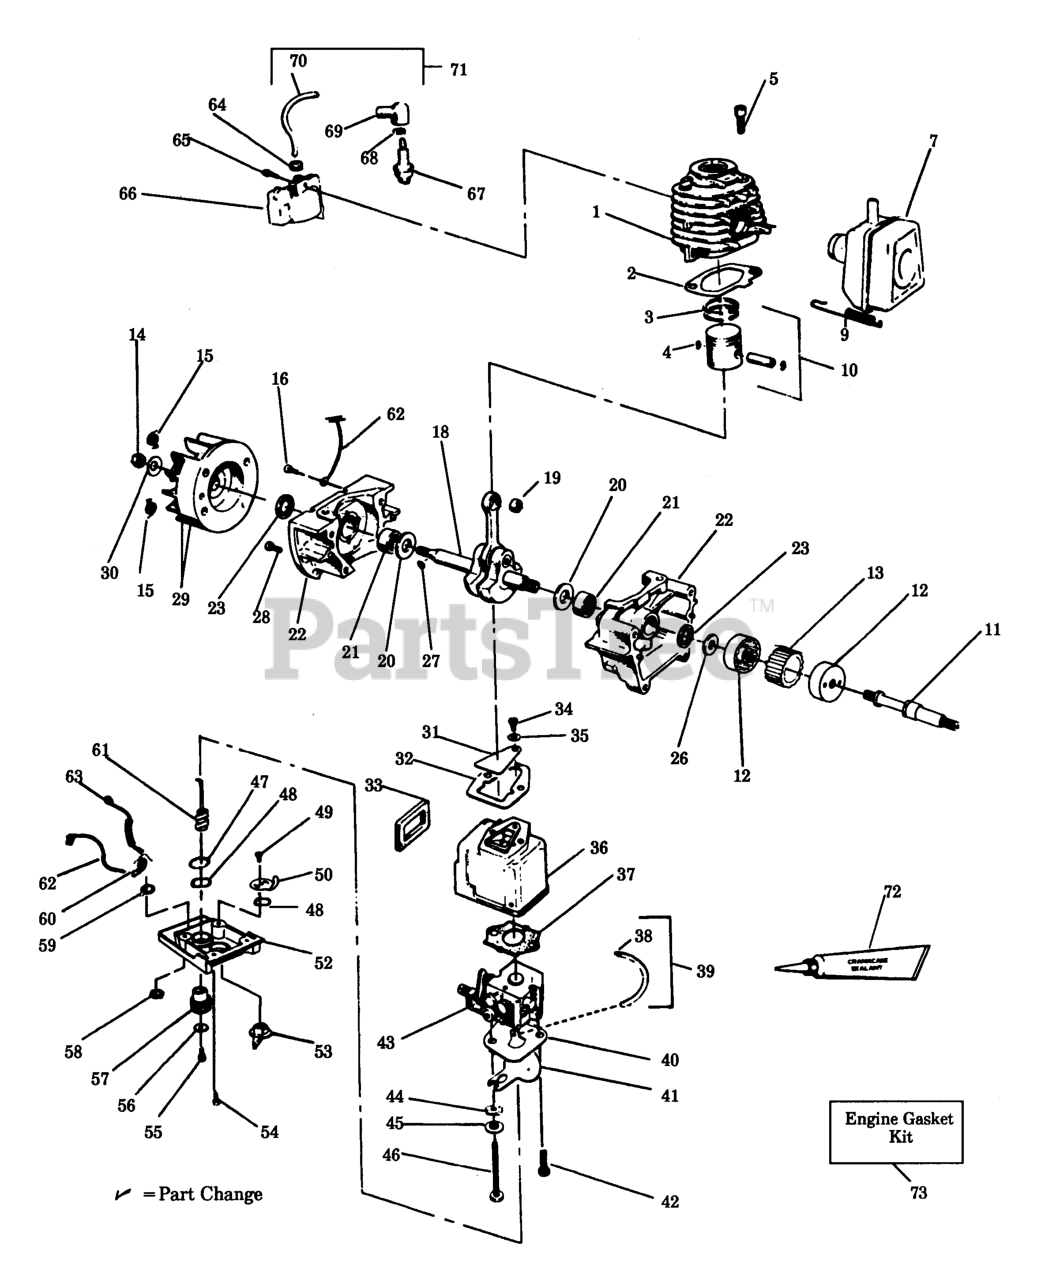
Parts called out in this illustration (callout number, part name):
1	CYL
2	CYL GASKET
3	RING-PISTON (22.2CC)
3	Piston Ring - Model 28HBV
4	WRIST PIN RET.
5	SCREW-1/4-20 X 13/16
7	KIT-MUFFLER BODY
9	SPRING
10	Piston Kit - Model 22HB
10	Piston Kit - Model 28HBV
12	Shaft Coupling
13	Plastic Coupling
15	SPRING STR DOG
16	SCREW-8-32 X 5/16 PAN H
18	ASSY-C'SHAFT & ROD
18	ASSY-C'SHAFT & BRG (SER
19	BEARING-PISTON PIN
20	WASHER THRUST
22	Crankcase Ass'y.
23	SEAL-CRANKCASE
27	KEY-FLYWHEEL
28	SCREW-10-24 X 5/8 FILL
29	FLYWHEEL ASSY
30	WASHER-FLYWHEEL
31	Reed Valve
32	CARB CASE GASKET
33	Carburetor Case Seal
34	SCREW-6-19X5/16PLAST PA
36	CASE-CARBURETOR
37	GASKET-CARBURETOR
38	FITTING-FUEL LINE
39	ASSY-FUEL LINE & FITTIN
40	Choke Guide Plate
41	SHUTTER-CHOKE
42	SCREW-10-24 X 2-23/64
43	CARBURETOR
45	SPACER-CARB. SCREW
46	SCREW-10-24 X 2-15/32
47	RING-EXTERNAL RETAINING
48	WAVE WASHER
49	SCREW-8-16 (PLASTITE)
50	ACTUATOR-CHOKE
52	COVER-CARBURETOR CASE
53	CHOKE KNOB
54	SCREW-8-18 X 5/18(RECES
57	KNOB-THROTTLE
58	NUT SWITCH MOUNT
60	Toggle Switch Kit
61	Throttle Wire Ass'y.
62	Ignition Wire
63	WIRE-GROUND
64	PLUG WIRE GROMMET
65	SCREW-COIL MTG
66	Ignition Module
67	SPARK PLUG (RCJ-8)
68	CONNECTOR
69	Spark Plug Boot
70	High Tension Lead Wire
71	High Tension Lead Ass'y.
72	RTV 3.35 OZ #598B
73	KIT-GASKET (SERVICE)
